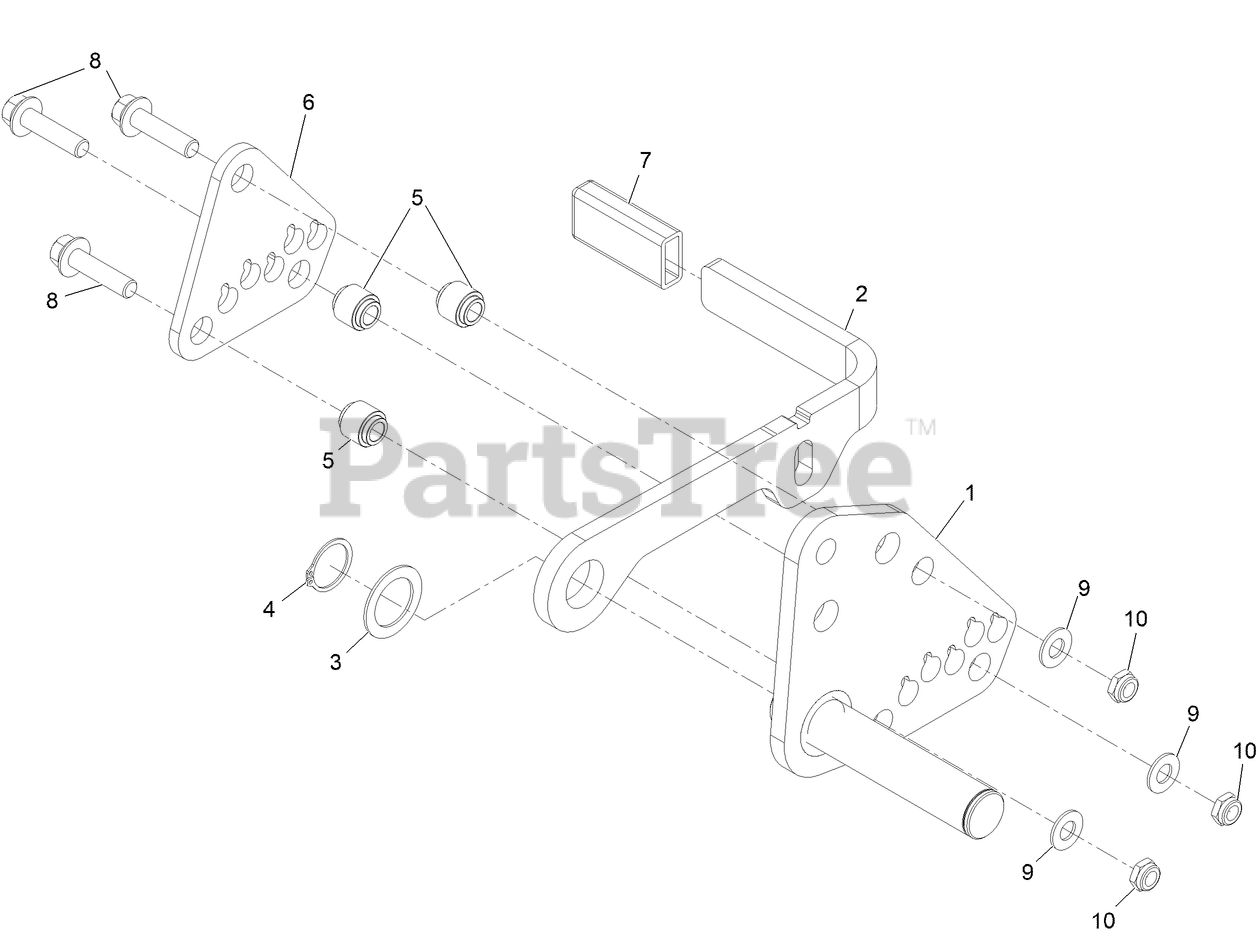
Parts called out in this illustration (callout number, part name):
1	PIVOT ASM-RH HOC
2	LEVER-RAKE, DECK
3	WASHER-THRUST
4	RING-RETAINING
5	SPACER-DOUBLE STEP
6	PLATE-RAKE ADJ, OUTER
7	GRIP-FLAT
8	SCREW-HHF
9	WASHER-PLAIN
